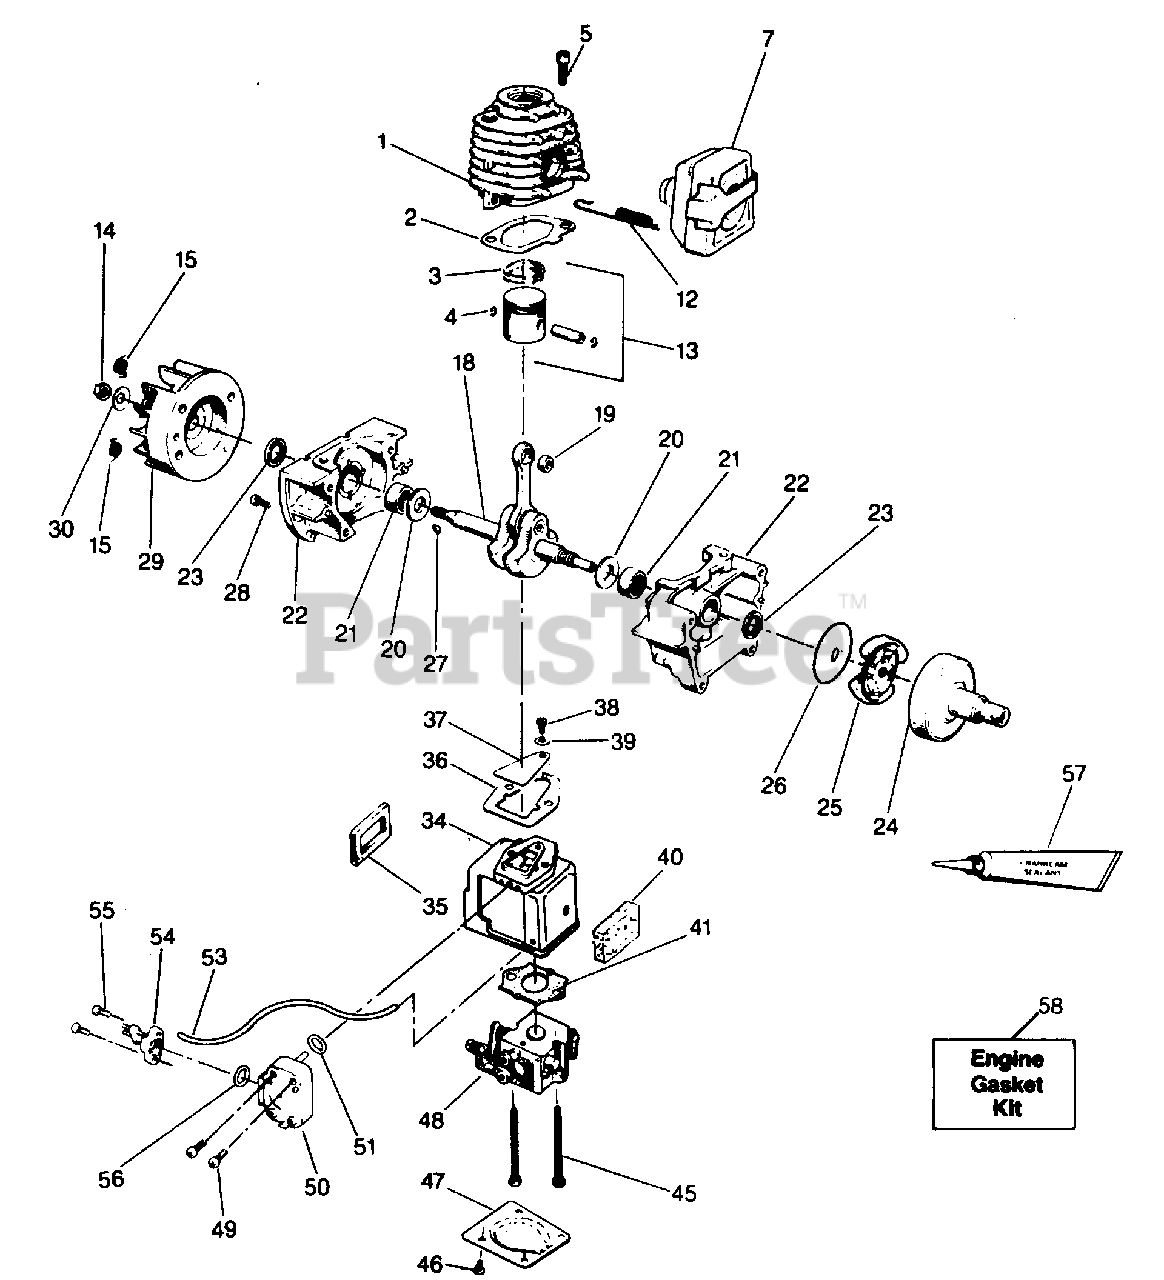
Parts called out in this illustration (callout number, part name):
1	Cylinder
2	Gasket - Cylinder
3	Ring - Piston
4	Retainer - Wrist Pin
5	Screw - 1/4 - 20 x 3/4 - Hex Soc. Hd. Cylinder
12	Spring - Muffler Attachment
13	Piston Kit (incl. #3, 4, Pin)
14	Nut - Flywheel
15	Spring - Starter Dog
18	Ass'y. - Crankshaft & Rod
19	Bearing - Wrist Pin
20	Washer - Thrust - Crankcase
21	Bearing - Crankcase
22	Crankcase Ass'y. (Incl. #21, 23 & Qty. 4 of #28)
23	Seal - Crankcase
24	Drum & Coupling Assembly
25	Clutch Assembly Kit (incl. Clutch Washer)
26	Kit - Clutch Washer
27	Key-Flywheel
28	Screw - 10 - 24 x 5/8 Fil. Hd. Crankcase
29	Flywheel Assembly (incl. #15)
30	Washer - Flywheel
34	Ass'y. Carburetor Housing & Eyelet
35	Seal - Carburetor Case
36	Gasket - Carburetor Case to Crankcase
37	Reed Valve
38	Screw - 6 - 19 x 5/16 - Pan Hd. - Reed Valve
39	Washer - Reed Valve Screw
40	See - Carb. Case (Sponge)
41	Gasket - Carburetor
45	Screw - 10 - 24 x 2-1/4" - Fil. Hd. - Carburetor
46	Screw - 8 - 18 x 9/16 - Pan. Hd - Carburetor Case Cover
47	Cover - Carburetor Case
48	Carburetor - WA - 149 - Cable
49	Screw - 8 x 18 x 1" - Accumulator
50	Accumulator Assembly (incl. #51 & 54)
51	O - ring (Orifice)
53	Fuel Line - Carburetor
54	Cap Assembly - Accumulator (incl. #56)
55	Screw - 8 - 16 x 9/16
56	O - Ring (Accumulator Chamber)
57	Sealant - Crankcase (not supplied with unit)
58	Engine Gasket Kit
